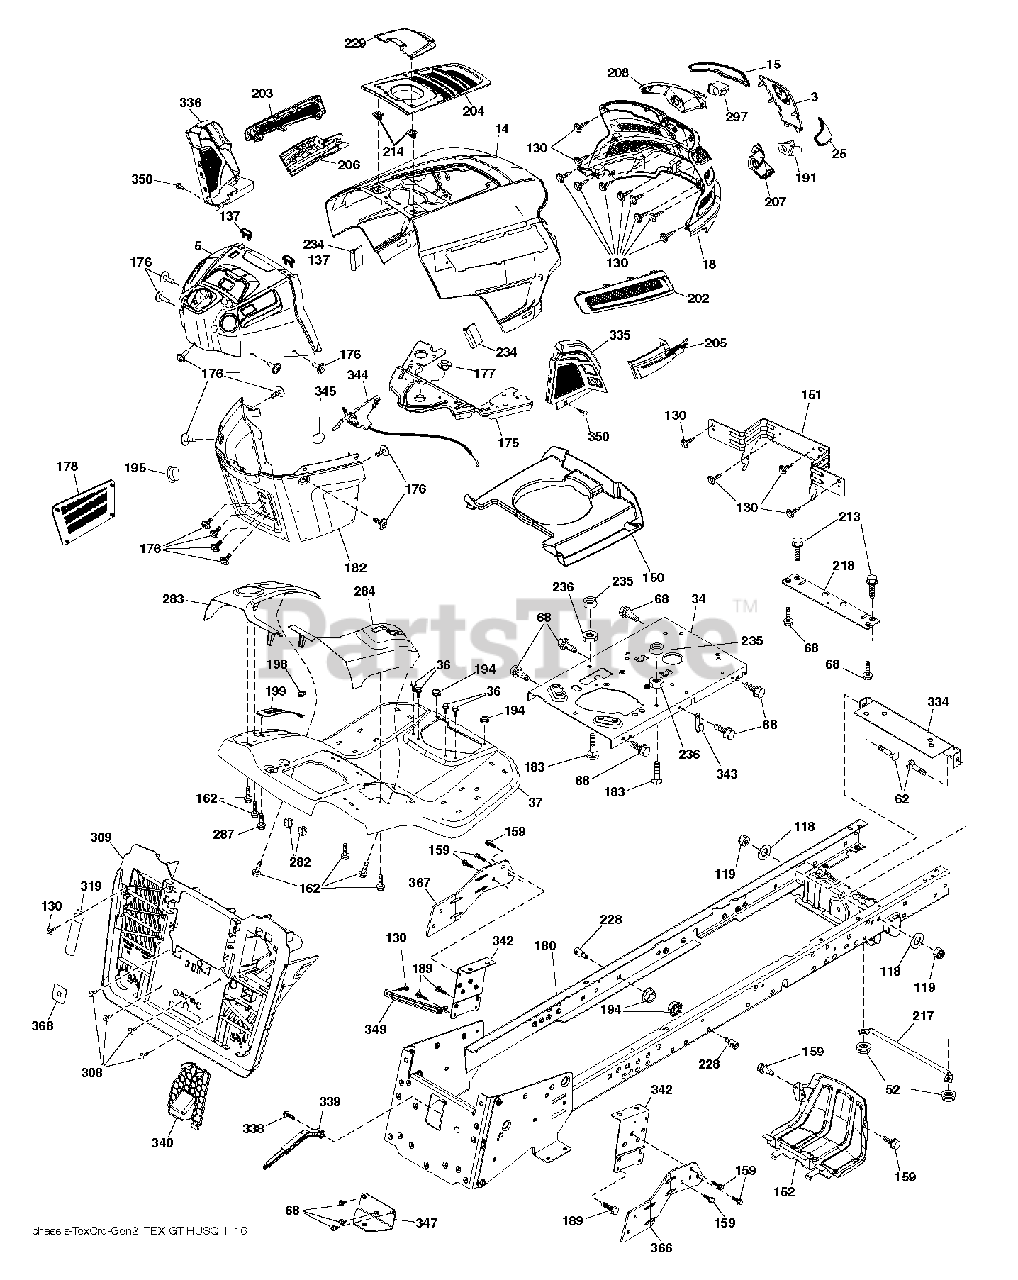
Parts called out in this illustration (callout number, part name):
3	APPLIQUE.SUBASM.GT.HUSQ.II
14	HOOD.ASM.HUSQVARNA.GT.TEX.ORAN
15	LENS.HEADLIGHT.LH.GTII.2011
18	GRILLE.SUBASM.GT.HUSQ.II
25	LENS.HEADLIGHT.RH.GTII.2011
34	PLATE.ENGINE.10GA.CRD.GENII
36	SCREW 5/16"
37	FENDER.TEX.SRD.CRD.FRN.GUARDS
52	LOCKNUT
62	BOLT D
68	SCREW LT
118	WASHER
130	SCREW.#10 X 0.750.BOS
137	BUMPER DASH
150	AIR.DUCT.GTV.BLACK
151	BRACKET.PIVOT.HOOD.GT.HUSQ.II
152	SHIELD.BROWNING.PNT.GT.V2
159	SCREW, 3/8-16X3/4
162	SCREW.HI-LO.CONSOLE
175	PLATE.CROSSMEMBER.HUSQ
176	SCREW.#10-24X5/8.RN.QU
177	BUSHING, STEERING
178	CARGO.ASM.NET.TXGT.W/C
180	WELDMENT.CHASSIS.TEX.CRD.GEN.2
182	DASH DASH LOWER
183	BOLT.5/16-18X1-1/4 FULL THD
189	SCREW
191	INSERT.REFLECTIVE.RH.HUSQ.GTII
194	NUT LOCK HEX FLANGE 5/16-18
195	PLUG.HOLE.DASH.LOWER.12V.BLK
198	INDICATOR.DECK.LIFT.RED
199	PLATE DECK LIFT
202	VENT.SIDE.RH.GT.HUSQ.II.
203	VENT.SIDE.LH.GT.HUSQ.II.498
204	VENT.TOP.EXTERNAL.FILL.GT2.GRE
205	SIDE.TRIM.RH.GT.HUSQ.II
206	SIDE.TRIM.LH.GT.HUSQ.II.GRAY
207	BEZEL LIGHT.RH.GT.II.MYLAR
208	BEZEL LIGHT.LH.GT.II.MYLAR
213	BOLT
214	CLIP.RETAINER.TINNER.
217	ROD.PIVOT.HOOD
218	X-PIECE.HOOD.STOP.NON/
228	STUD.FASTNER.W/ANTI-ROTATE
229	LID.EXT.FILL.GT.HUSQ2.BLACK
234	BUMPER.HOOD.TEX.HUSQVARNA
235	SPACER FENDER
236	NUT.CENTERLOCK.5/16-
282	CLIP.RETAINER.CONSOLE.LT.HUSQ
283	CONSOLE.DECKLIFT.CRDII.498
287	SCREW 1/4X20
297	INSERT.REFLECTIVE.LH.HUSQ.GTII
308	BOLT, 5/16-18 X 1 3/4
309	BACKPLATE.ASM.CRDII.ANTIROTAT
319	LEVER.BAG.CRDII.ANTIROTATION
334	BRACKET.ENGINE
335	COVER-LH.LOWER.DASH.GT2.BLACK
336	COVER.LOWER.DASH.RH.BLACK
338	BOLT BOLT SHOULDER
339	LEVER LEVER BAGGER
340	BATTERY.DOOR.TEX.CRD.GEN.2,1
342	SUPPORT SUPPORT FENDER
343	CLIP CLIP
344	CONTROL.EZ.MULCH.TEX/CRD
345	RP KNOB.OVAL.TAPERED.3/8-16BLK
347	HITCH HITCH TOW TEX CRD GEN 2
349	BRACKET.SUPPORT.LRVB/CRD
350	CLIP.X-MAS.TREE
366	BRACKET.RH.FRONT.BAGGER.BLACK
367	BRACKET.LH.FRONT.BAGGER.BLACK
368	FULL.LEVER.BAGGER.TEX.CRD
